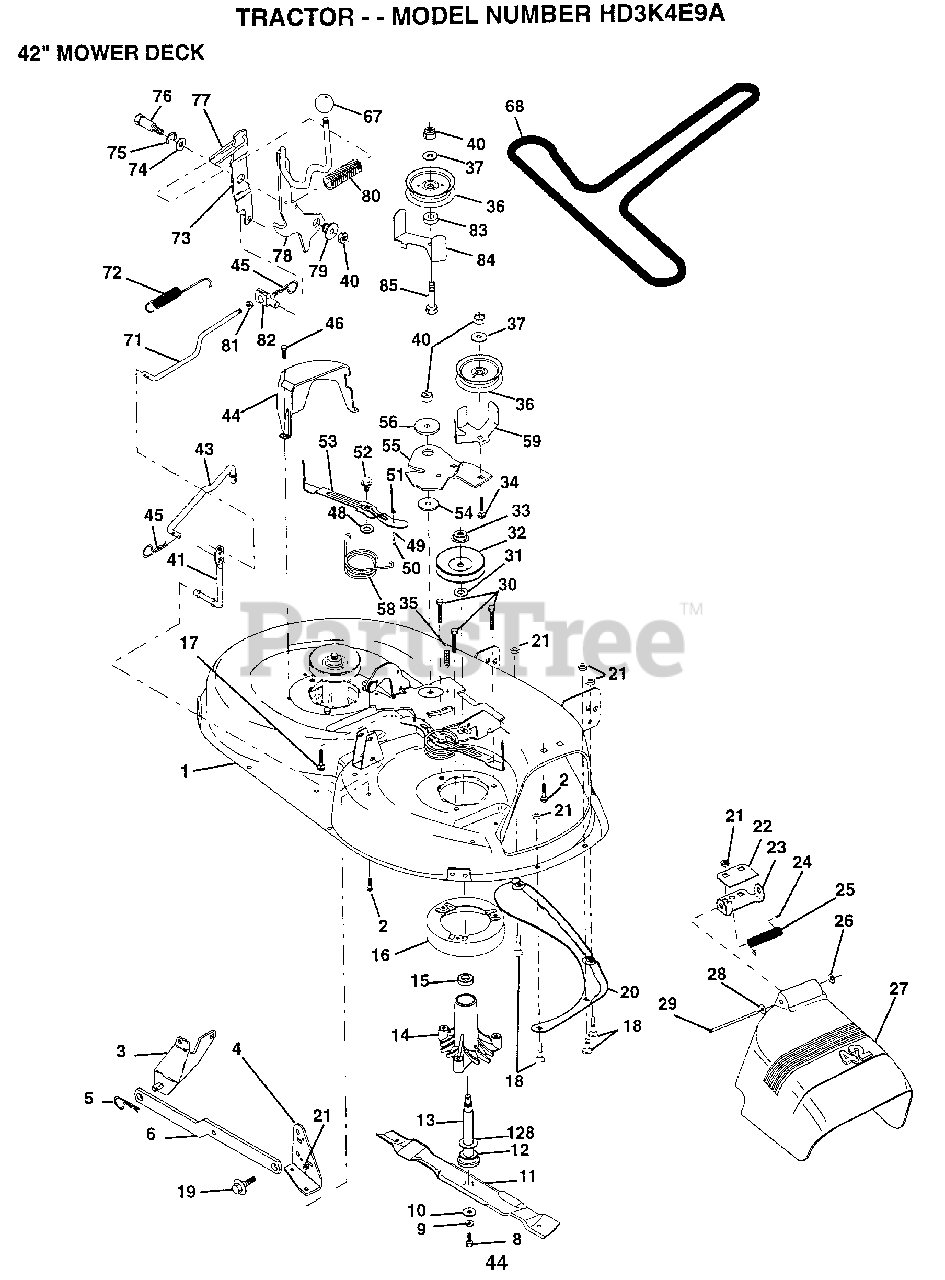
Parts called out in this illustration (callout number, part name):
1	DECK.WELD.42.
2	BOLT
3	BRKT ASM SWAY BAR
4	BRKT DECK SW BAR
8	BLADE BOLT
10	WASHER.HARD.BLADE
11	"BLADE.42"" HIPERF"
12	BEARING.BALL
14	HSG ASM MANDREL
15	BEARING
16	STRIPPER RND MWR
17	BOLT RDHD 3/8-16
18	BOLT
19	BOLT SHD 5/16-18
22	STIFFENER BRKT
23	DEFLECTOR BRKT
24	CAP-SLEEVE LT
25	SPRING TORSION
26	NUT PUSH M
27	DEFLECTOR.SHIELD
28	WASHER
29	HINGE ROD
31	WASHER
32	PULLEY.MANDREL.42
34	BOLT
35	XMAS TREE FASTNER
36	FLAT IDLER PULLEY
37	WASHER
41	PIVOT ROD
43	ROD CLUTCH W/NIBS
44	GUARD MAND LH BLK
45	RETAINER M
46	SCREW.1/4-20X5/8
48	HARD SMALL WASHER
50	SHOULDER BOLT
51	LOCKNUT
52	BOLT.SHLD.5/16-18
53	BRAKE PAD ARM ASM
54	HARDENED WASHER
56	SPACER RETAINER
58	SPRING TORSN BRAK
59	GUARD IDLER TUV
67	KNOB T (1/2-HOLE)
68	BELT.V.T-PATH
71	ROD CLUTCH 38/42
72	RETURN SPRING
73	CLUTCH ARM SECOND
74	WASHER
75	RING
76	SHOULDER BOLT
77	SPRING KEEPER
78	LEVER ASM CLT PRM
79	BUSHING
80	SPRING.CLUTCH.MWR
81	NUT
82	TRUNION ADJ
83	WASHER
85	BOLT RDHD 3/8-16
128	WASHER.FELT.
